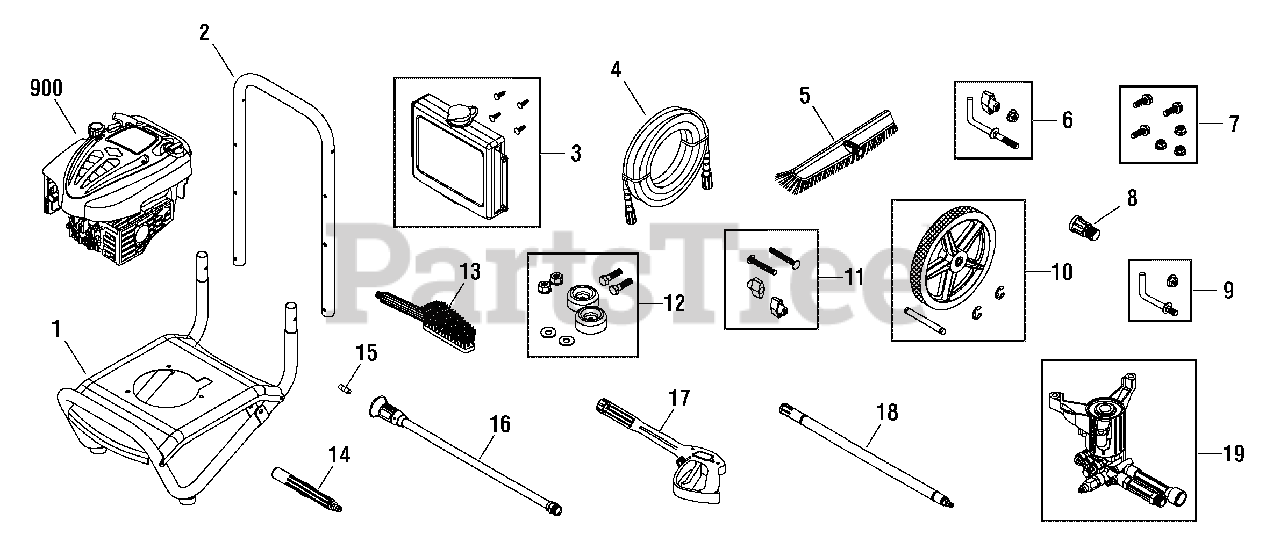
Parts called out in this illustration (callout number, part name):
4	HOSE
5	BRUSH, Broom
7	KIT, Hardware, Pump Mounting
8	ADAPTER, Extension
11	KIT, Hardware, Handle
12	KIT, Vibration Mount
13	BRUSH, Utility
16	WAND, Adjustable
17	GUN
18	EXTENSION, Wand
19	PUMP
900	* ENGINE
